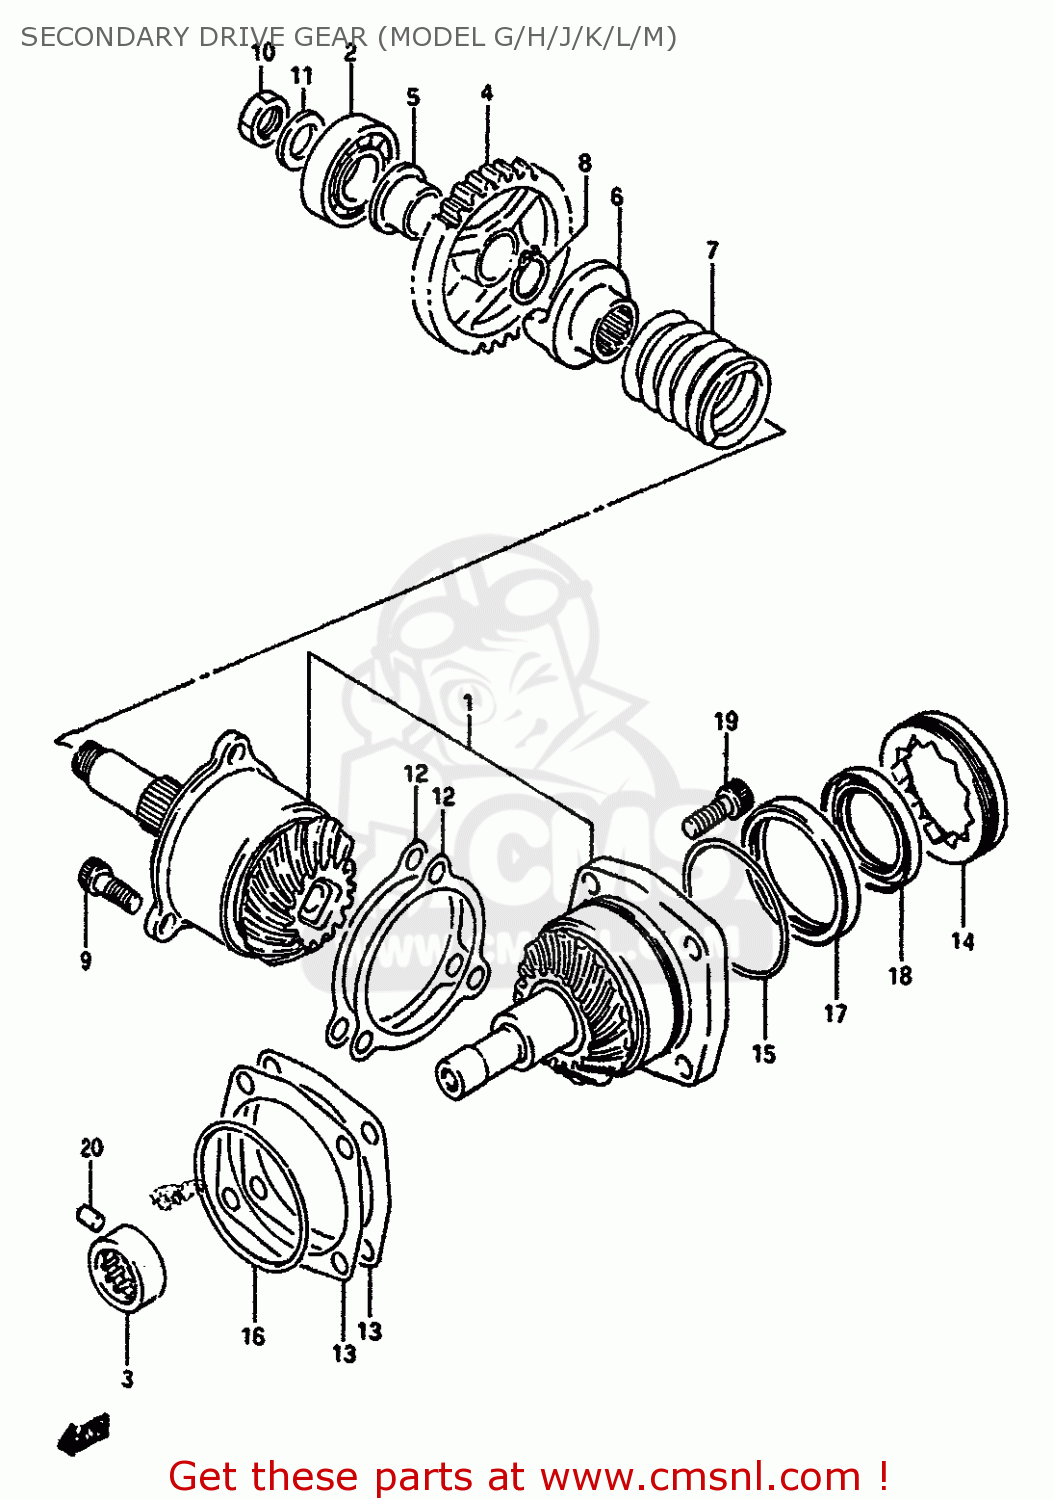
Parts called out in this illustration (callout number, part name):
1	GEAR & HOUSING SET,SECONDARY
2	BEARING(20X52X15)
3	BEARING(20X34X16)
4	GEAR,REDUCTION DRIVEN(NT:30)
5	BUSH,REDUCTION DRIVEN GEAR
6	DOG,OUTPUT CAM
7	SPRING
8	CIRCLIP,21MM
9	BOLT
10	NUT
11	WASHER(16X29X4)
12	SHIM,SECONDARY DRIVE
13	SHIM,SECONDARY DRIVEN HOUSING
14	STOPPER,SEC DRIVEN BEARING
15	O RING(D:1.2,ID:59.6)
16	O RING(D:2.1,ID:66.2)
17	HOUSING,OIL SEAL
18	SEAL,OIL(38X54X8.5)
19	BOLT
20	PIN
